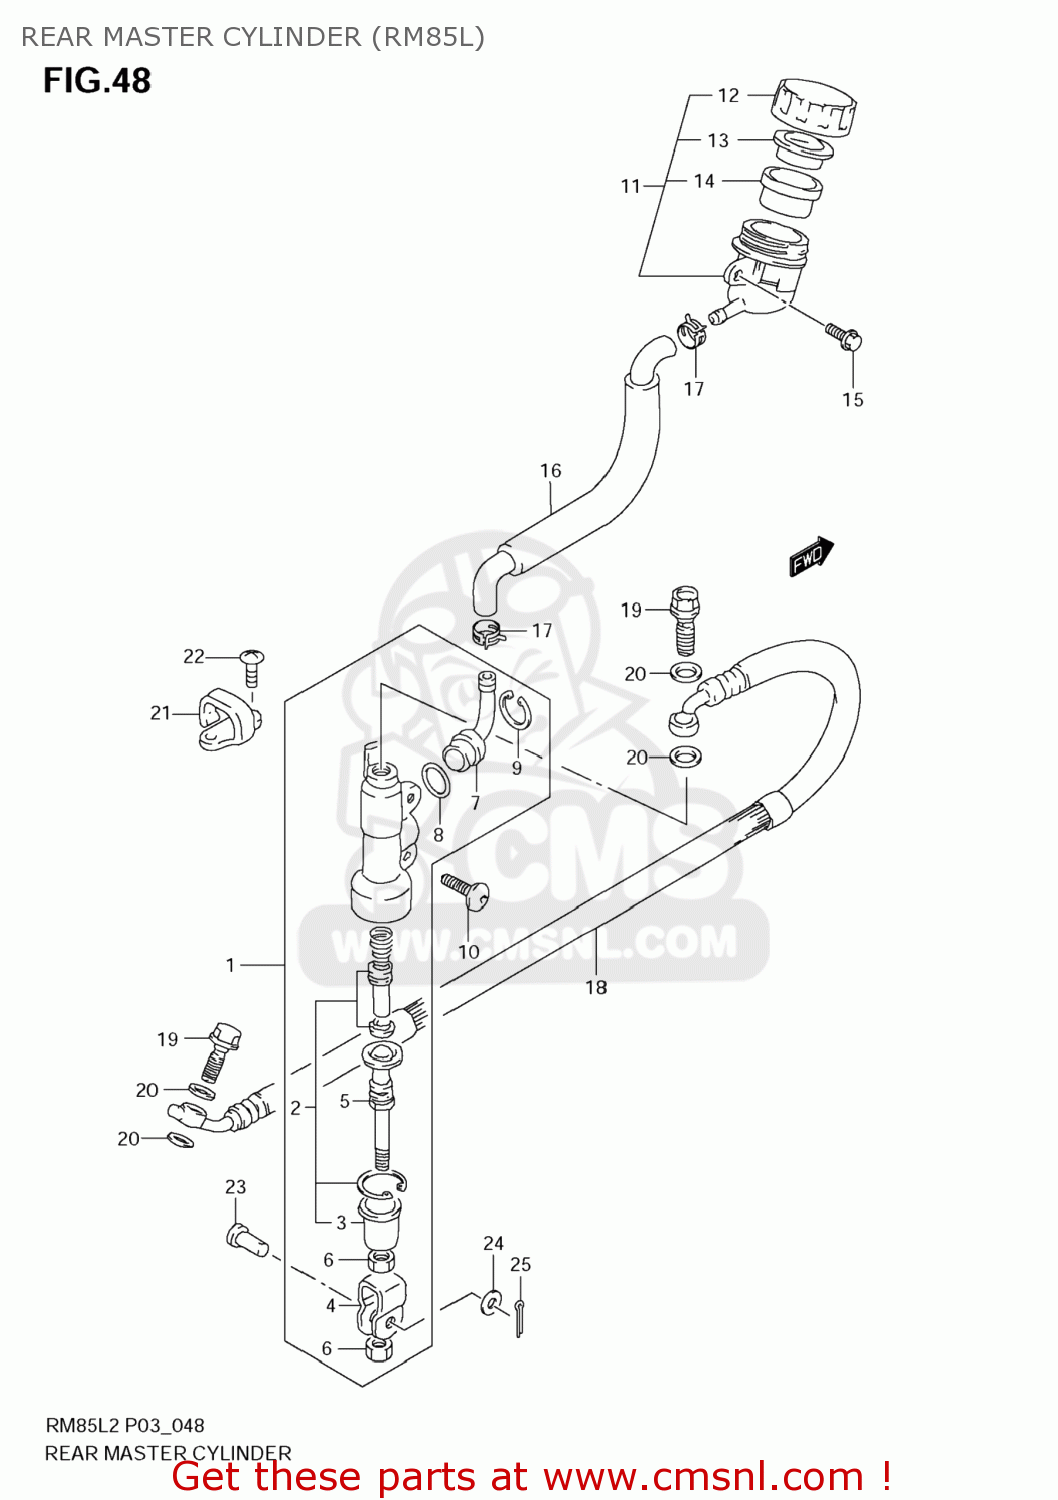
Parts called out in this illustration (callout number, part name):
1	CYLINDER ASSY,RR MASTER
2	PISTON/CUP SET
3	BOOT
4	YOKE
5	ROD,PUSH
6	NUT
7	CONNECTOR
8	O RING
9	CIRCLIP
10	SCREW(6X16)
11	TANK ASSY,RR BRAKE RESERVOIR
12	CAP
13	PLATE
14	DIAPHRAGM
15	BOLT(6X12)
16	HOSE,RESERVOIR TANK
17	CLAMP,RESERVOIR HOSE
18	HOSE,RR BRAKE
19	BOLT UNION
20	WASHER(10X15X1.5)
21	GUIDE,RR BRAKE HOSE
22	SCREW
23	PIN(8X20)
24	WASHER(8.5X14X1.6)
25	PIN
